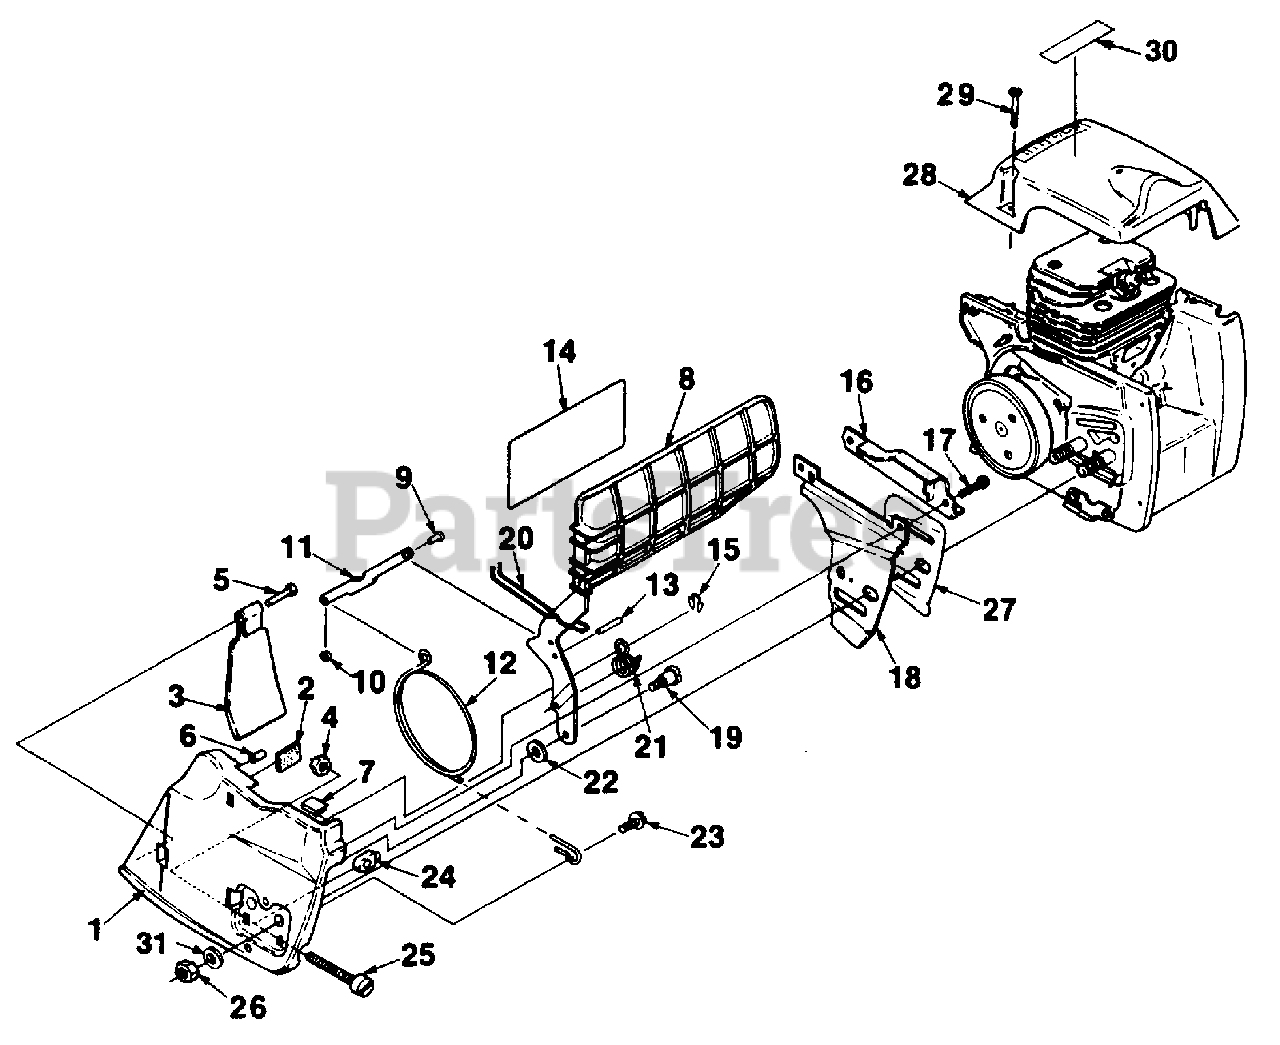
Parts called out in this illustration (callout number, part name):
1	COVER- Drivecase
2	BUMPER- Foam
3	SHIELD- Sawdust
4	NUT- Hex (1/4-20)
5	RIVET- Pan hd.
6	BUSHING
7	CLIP- Spring
8	GUARD- Hand (w/brake)
9	RIVET- Truss hd.
11	LINK- Pivot
12	BAND- Brake
13	PIN- Dowel
15	RING- Retaining
17	SCREW- Pan hd. (6-32 x 3/8")
18	PLATE- Guide bar (outer)
19	SCREW- Shoulder
21	SPRING- Torsion
22	WASHER- Flat
23	SCREW- (1/4-20 x 3/8")
24	PIN- Guide bar adjusting
25	SCREW- Guide bar adjusting
27	PLATE- Guide bar (inner)
28	COVER- Cylinder
30	DECAL- Ansi
31	WASHER- Flat
